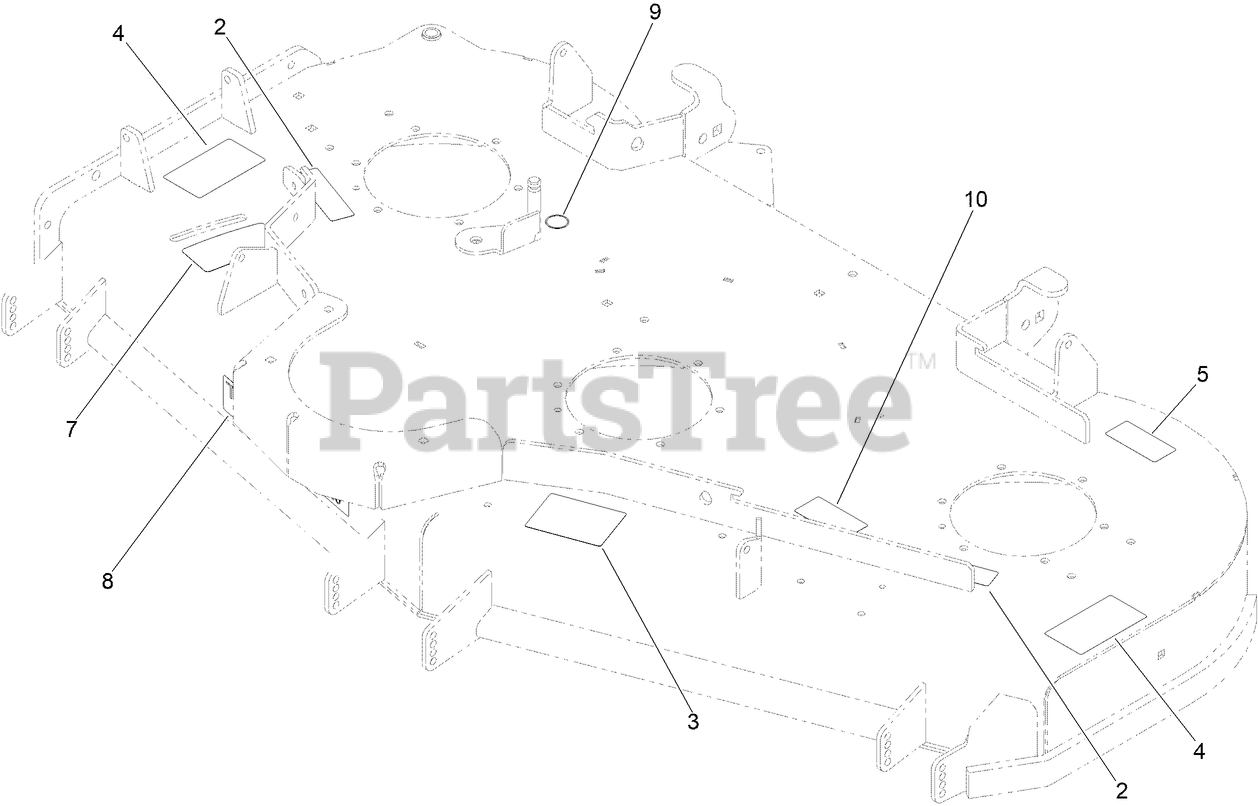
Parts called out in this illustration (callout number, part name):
2	DECAL-COVER, MISSING
3	DECAL-SCALP, ANTI
4	DECAL-DANGER THROWN OBJECTS
5	DECAL-BOLT TORQUE
7	DECAL-ADJUSTMENT, BAFFLE
9	DECAL-GREASE
10	DECAL-BELT 60 SIDE
